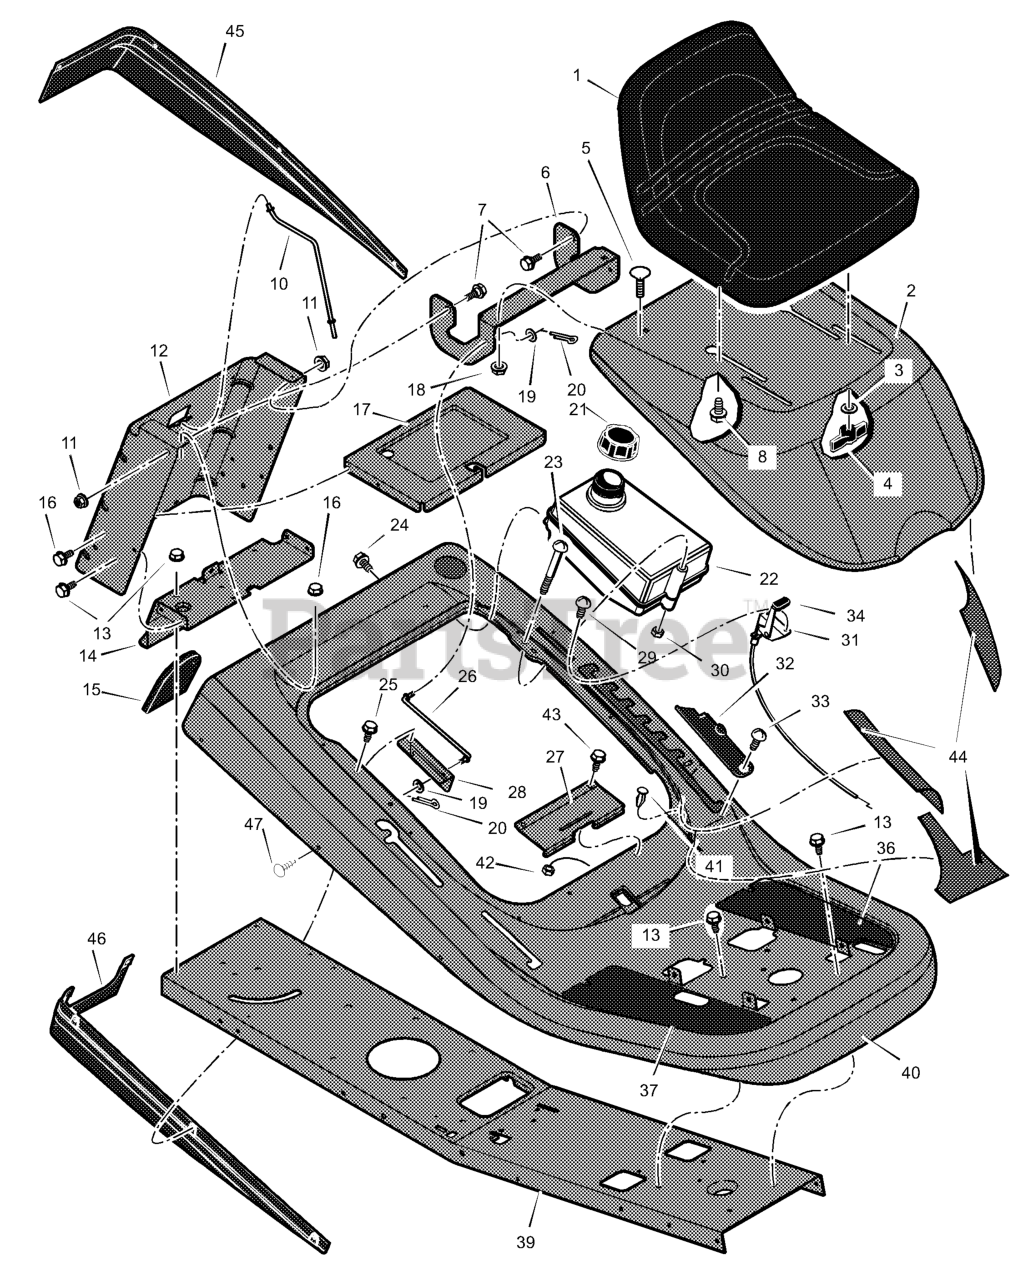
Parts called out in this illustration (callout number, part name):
1	Seat
3	Washer
4	Bolt, Wing
5	Bolt, Carriage
6	Bracket, Hinge
7	Bolt, Shoulder
8	Bolt, Shoulder
10	Rod, Battery
11	Nut, Flange
12	Plate, Rear
14	Plate, Hitch
17	TRAY, Battery
18	Nut, Flange
19	Washer
20	Pin, Cotter
21	Cap, Fuel Tank
22	Tank, Fuel
23	Screw
26	Rod, Hood Prop
27	Spring, Seat Deck
28	Bracket, Prop Rod
30	Nut, NY-Lock
31	Control, Throttle
32	Cover, Detent (Black)
33	Bolt, Shoulder
36	Footmat, Left
37	Footmat, Right
41	Bumper
42	Nut
43	Screw
44	Kit, Foil Heat Shield
45	Trim, Left
46	Trim, Right
47	Fastener, Panel
